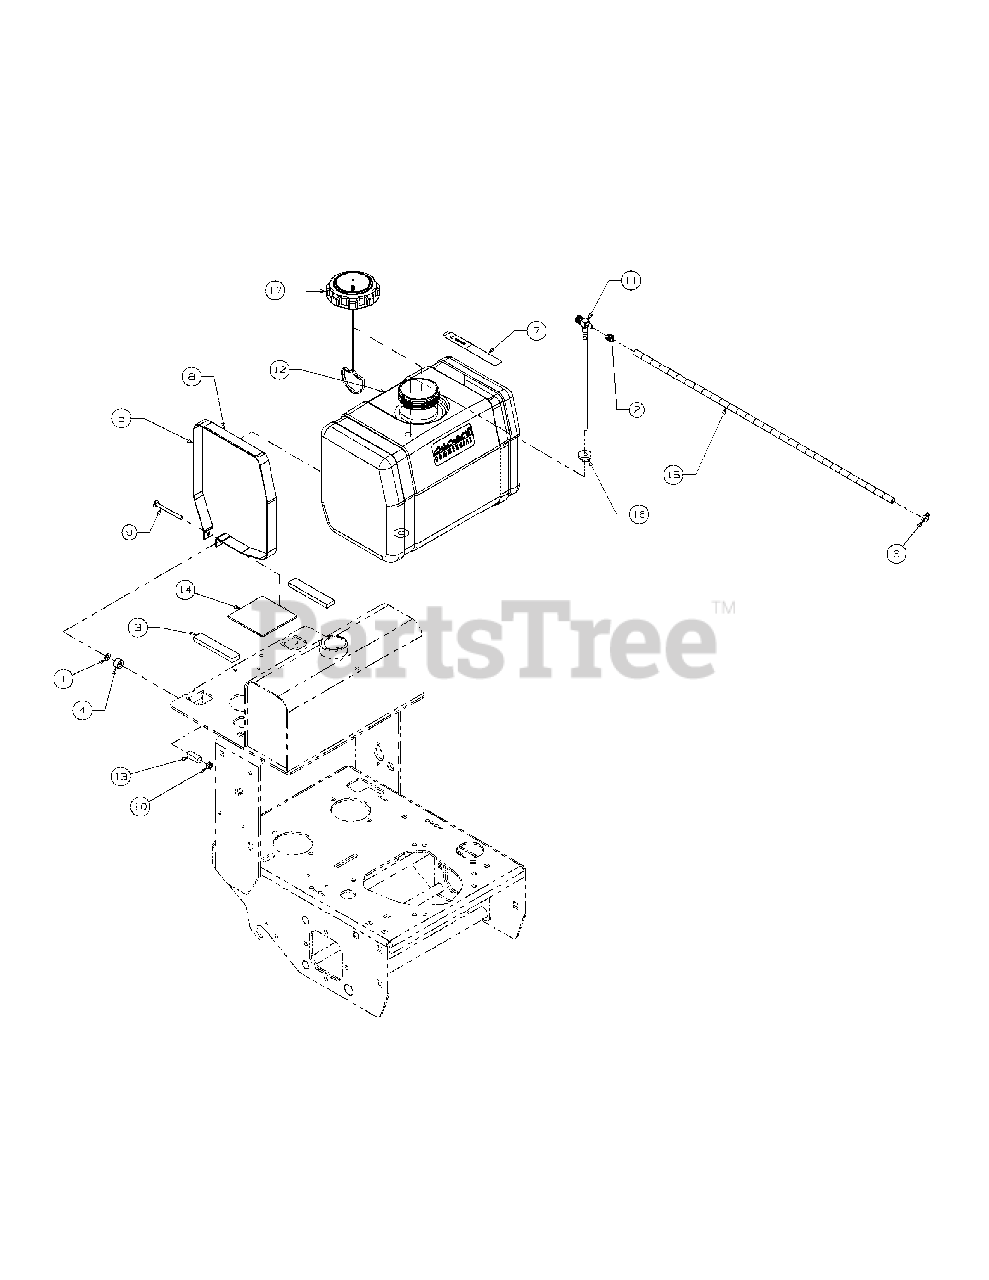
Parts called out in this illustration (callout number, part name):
1	Flat Washer, SAE 5/16
2	Uni-Clamp
3	Stop Pad, Rubber
5	Fuel Tank Strap
6	Hose Clamp, 1/4-5/8, SS
7	Mower Warning Label, Turn off Engine
8	Mower Instruction Label, Fuel Valve
9	Carriage Bolt, 1/4-20 x 3.00
10	Lock Nut, 1/4-20, Hex Flange Lock
11	Shutoff Valve
12	Fuel Tank
13	Compression Spring, .625 OD x .390 ID
14	Rubber Strip
15	Fuel Hose, 18"
16	Grommet Fuel Tank
17	Fuel Cap, 3.5, Tethered
